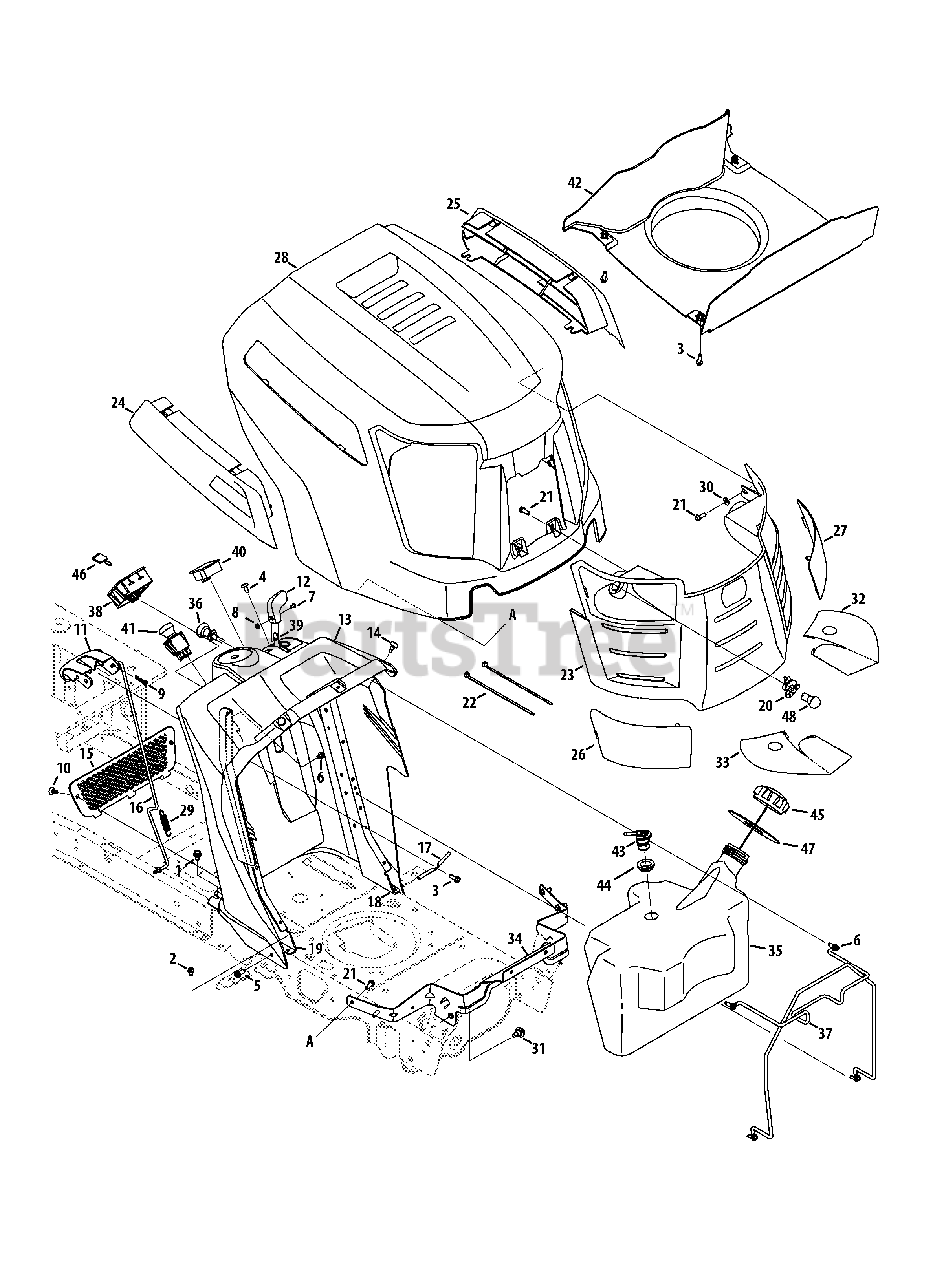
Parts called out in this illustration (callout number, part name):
1	Screw, Self-tapping, 5/16-18, .750
2	Screw, Self-tapping, 1/4-20, 0.500
3	Screw, HL, 1/4-15, 0.750
4	Screw, Ab, 1/4-14, 0.625,
5	Screw, Self-tapping, 5/16-18, 0.750,
6	Screw, Self-tapping, 1/4-20 x .625
7	Screw, Mach, #8-32, 0.375
8	Nut, Hex, #8-32
9	Pin, Cotter, Bow-Tie 72
10	Clip, Ratchet, .250 Dia
11	Lever, Dash, Cruise/Brake
12	Knob, Throttle
13	Dash Panel, A-Style, Elect PTO
14	Bumper, .62 Dia X .3
16	Rod, Control, Latch Cub
17	Rod, Lever, Bent
18	Support, Dash, Plate LH
19	Support, Dash, Plate RH
20	Socket, Lamp
21	Screw, 1/4 Dia, .750
22	Tie, Cable, Push Mount 7.5 Lg
23	Grille Ass’y (Incl. 26, 27, 32 & 33)
24	Scoop, Hood, RH A-Style
25	Scoop, Hood, LH A-Style
26	Lens, Hood, RH A-Style
27	Lens, Hood, LH A-Style
28	Hood, A-Style
29	Spring, .500 Dia. x 2.733
30	Washer, Flat, .271, .630, .065
31	Screw, Shoulder, .43x.29, 5/16-18
32	Reflector, Cub A Style, LH
33	Reflector, Cub A Style, RH
34	Bracket, Pivot, Hood A-Style
35	Tank, Fuel, 3.30 Gal.
36	Control, Choke, 40.5 x 2, Yellow
37	Rod, Support, Fuel Tank
38	Module Switch, Ignition
39	Cable, Throttle, 39"
40	Meter, Indicator
41	Switch, Electric PTO, Yellow
42	Plenum, A-Style, B&S Intek Twin
43	Valve, Rollover Grommet
44	Grommet, Rubber, 23.0 ID
45	Cap, Fuel
46	Key, Assembly
47	Gasket, Fuel Tank
48	Lamp, 12v
